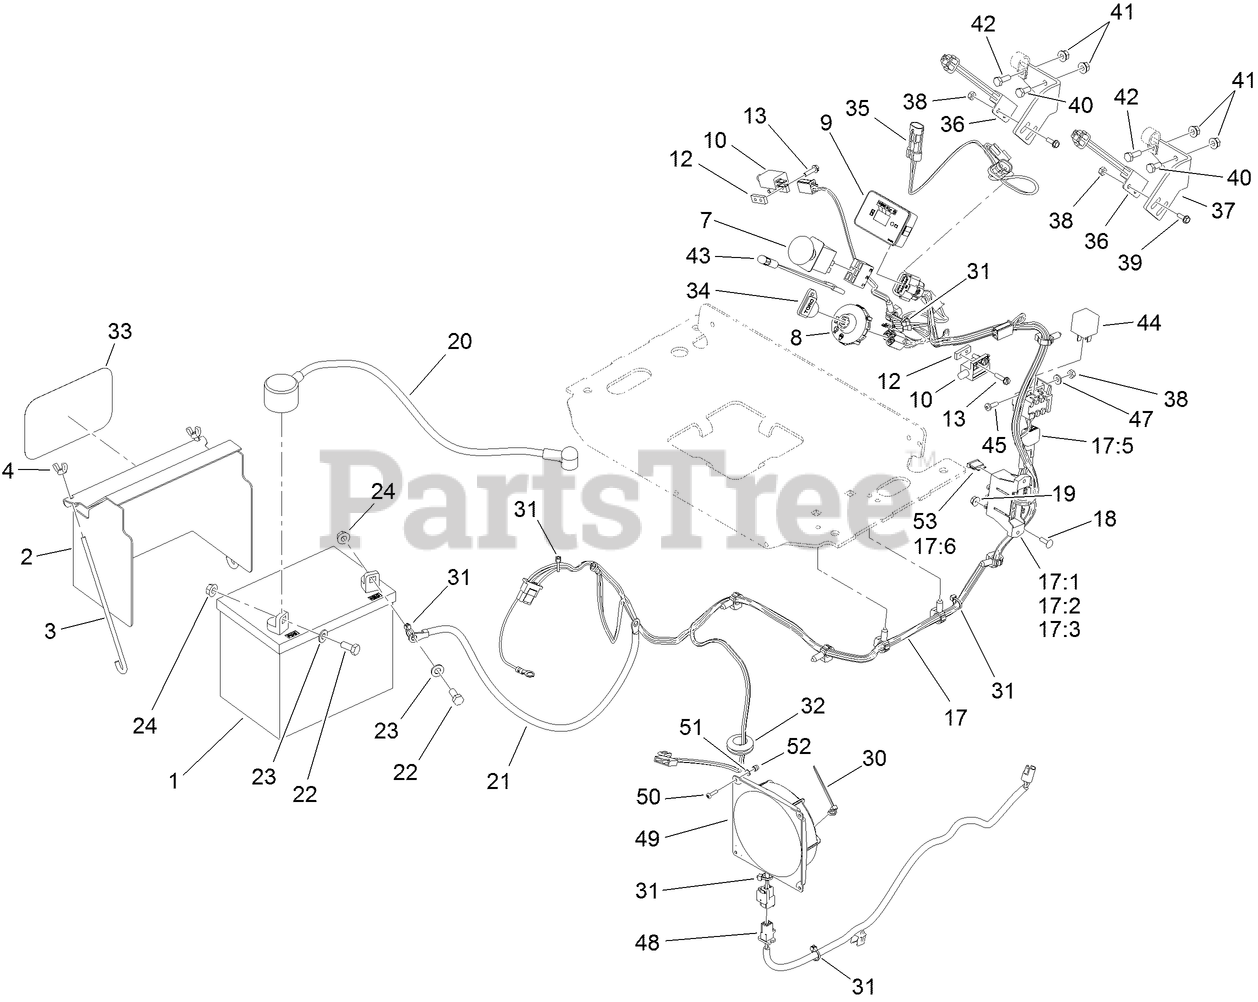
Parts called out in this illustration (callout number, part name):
1	BATTERY-DRY
2	COVER-BATTERY
3	BOLT-HOLDDOWN
4	WINGNUT
7	SWITCH-PTO, ON-ON-(ON)
8	SWITCH-IGNITION
9	MODULE-HOUR METER
10	SWITCH-CLOSED, NORMALLY
12	PLATE-TAPPED
13	SCREW-HWH
17	HARNESS-WIRE, EFI
17:1	FUSE-BLADE, 30 AMP
17:2	FUSE-BLADE, 25 AMP
17:3	FUSE-BLADE, 10 AMP
17:6	FUSE-BLADE, 15 AMP
18	BOLT-CARR
19	NUT-HF
20	CABLE-BATTERY, POSITIVE
21	CABLE-BATTERY, BLACK
22	SCREW-HH
23	WASHER-PLAIN
24	NUT-HHF, SMOOTH
30	TIE-CABLE
31	TIE-CABLE
32	GROMMET
33	DECAL
34	KEY-IGNITION
35	HARNESS-WIRE, NEUTRAL SWITCH
36	SWITCH-PROXIMITY
37	BRACKET-MOUNT, SWITCH
38	NUT-LOCK, NI
40	SCREW-HH
41	NUT-HHF
42	SCREW-HH
43	INDICATOR-LED, RED
45	SCREW-PPH
47	WASHER-FLAT
48	HARNESS-WIRE, FAN
49	FAN-ELECTRIC
50	SCREW-PPH
51	WASHER-FLAT
52	NUT-LOCK
53	FUSE-BLADE, 15 AMP
